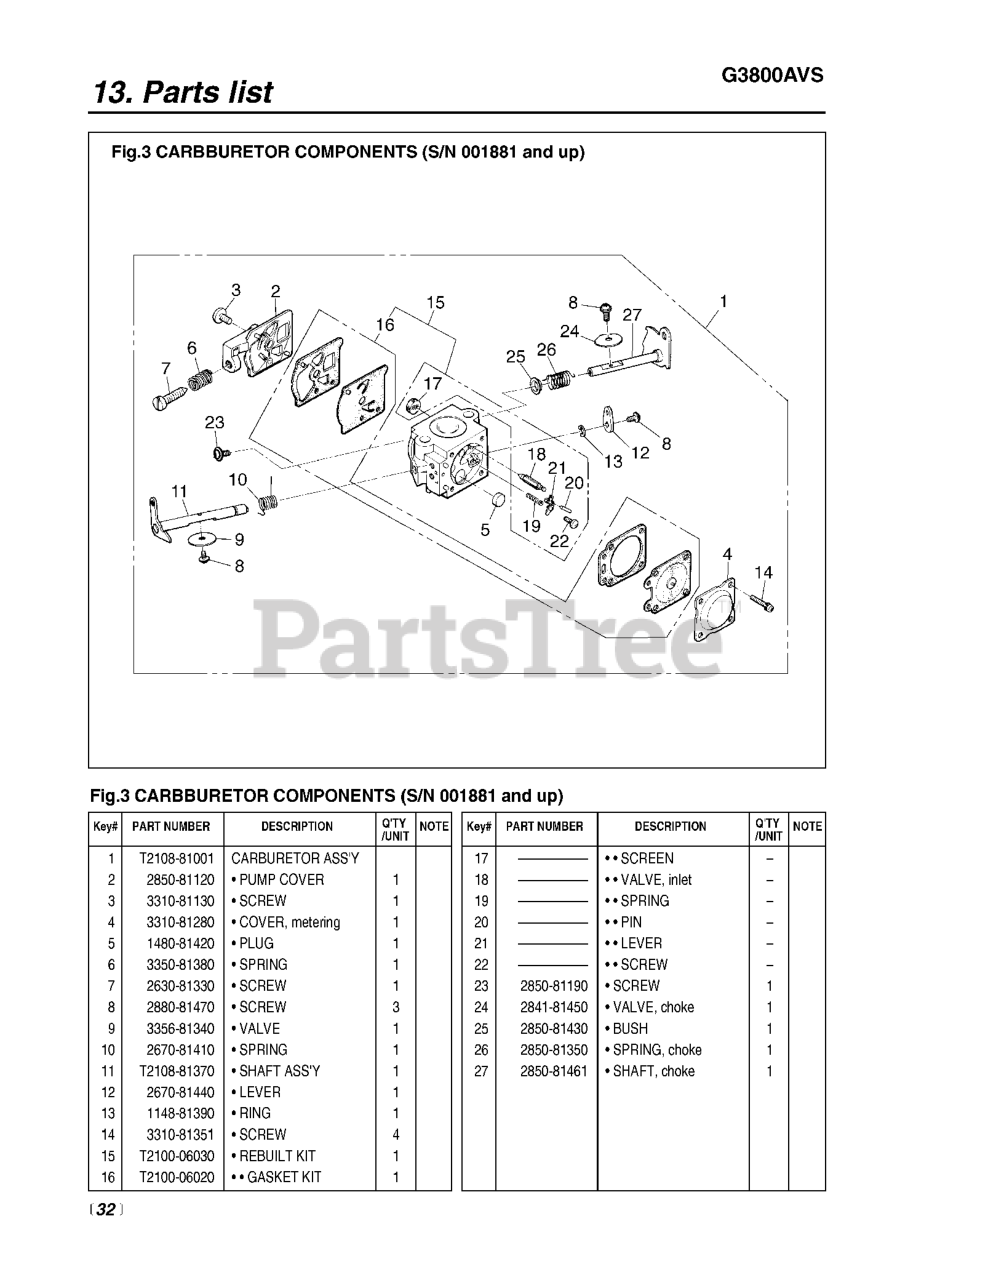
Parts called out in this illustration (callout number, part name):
1	CARBURETOR ASSY(RPL-T210881000
8	SCREW
9	VALVE, THROTTLE
10	SPRING RETURN
11	THROTTLE SHAFT ASSY.
14	SCREW ASSY
15	REBUILT KIT
17	RedMax TBD
18	RedMax TBD
19	RedMax TBD
20	RedMax TBD
21	RedMax TBD
22	RedMax TBD
